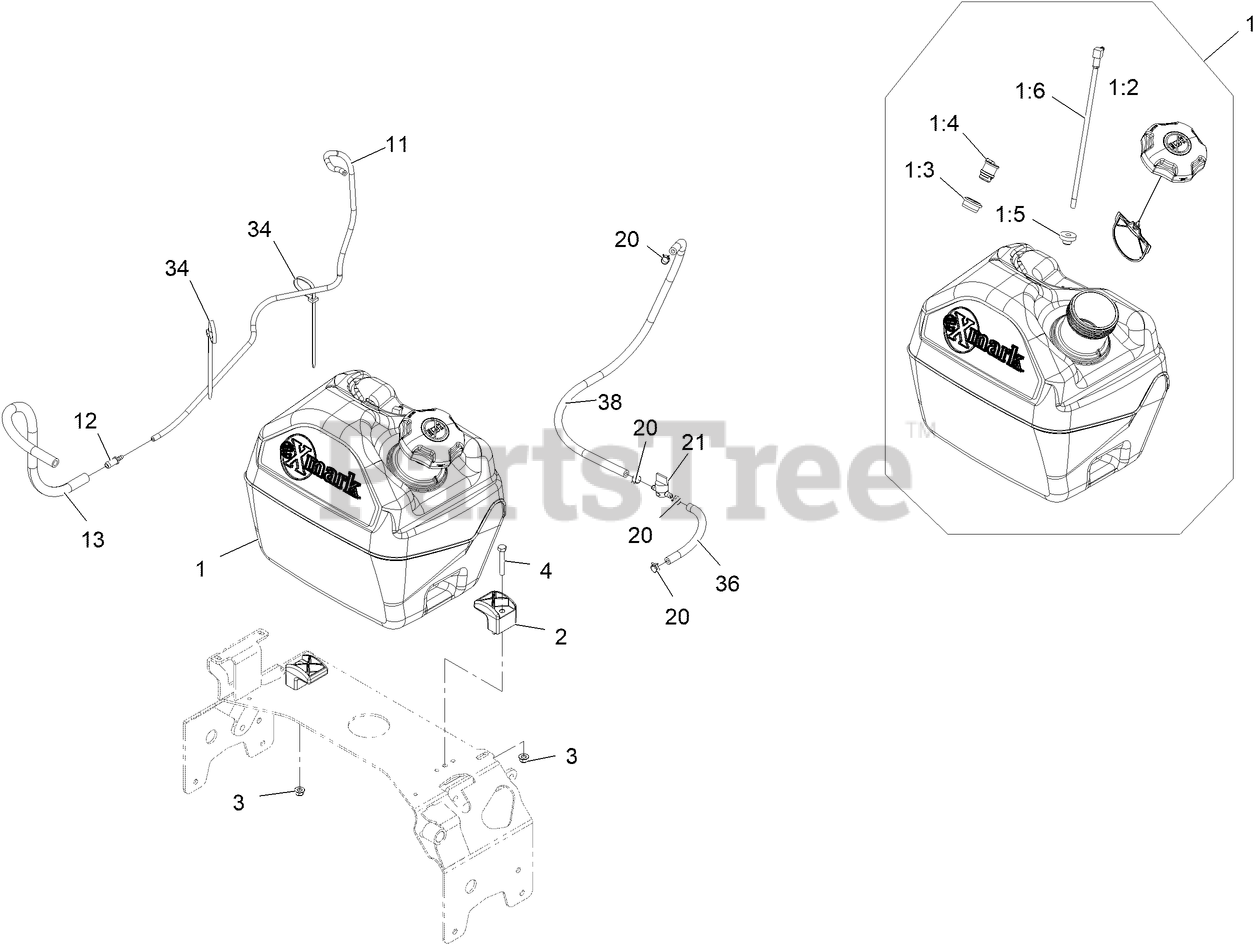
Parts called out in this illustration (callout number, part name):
1	ASM, FUEL TANK 5 GAL
1:2	CAP-FUEL, RATCHETING
1:3	GROMMET
1:4	VALVE-VENT, FUEL
1:5	BUSHING
1:6	FITTING, FUEL W/LINE AND SCREEN
3	NUT-HF, NI
4	SCREW-HH
11	HOSE, EMISSIONS
12	FITTING-STRAIGHT
13	HOSE-FUEL
20	CLAMP-HOSE
21	VALVE-FUEL
34	TIE-CABLE
36	HOSE-FUEL
38	HOSE-FUEL
